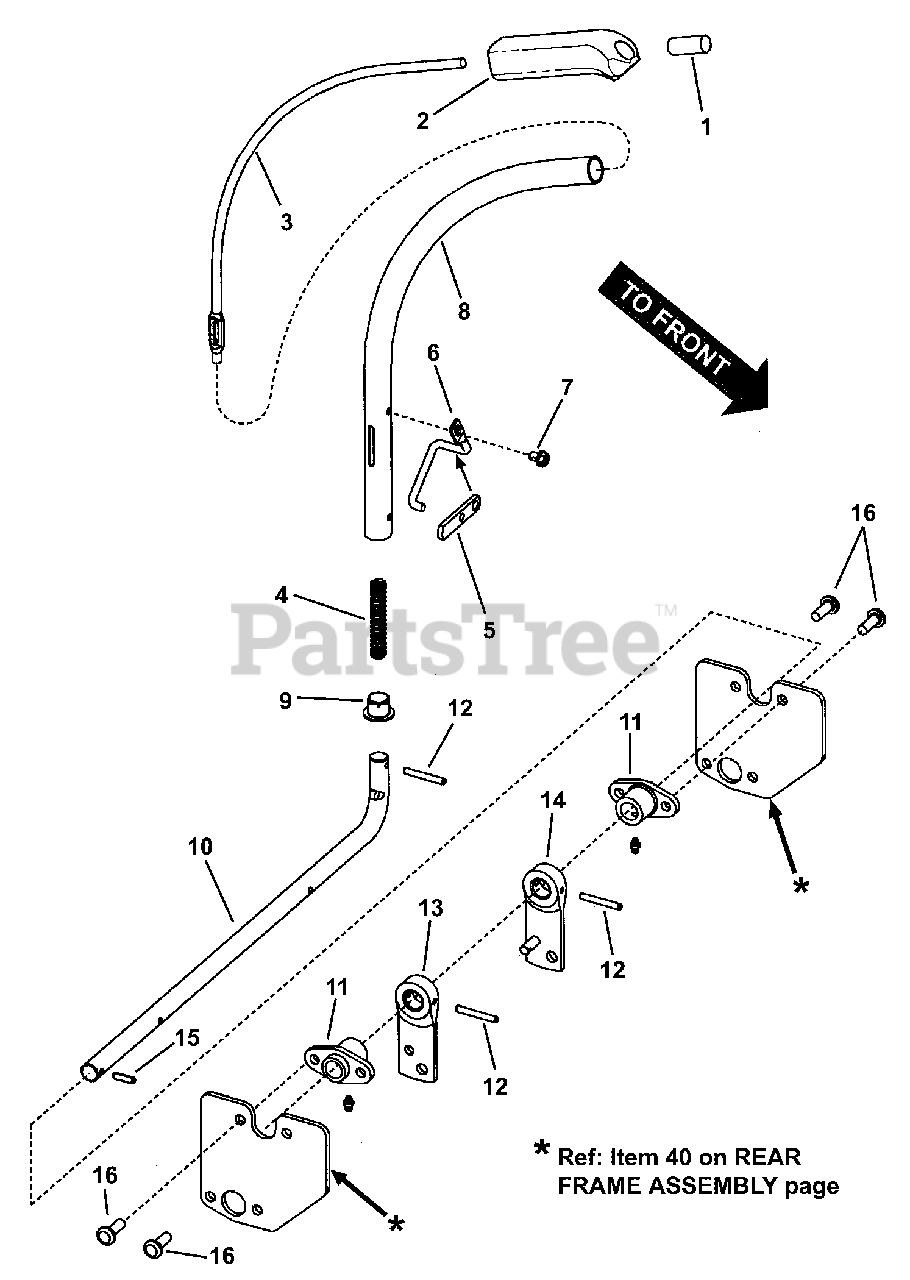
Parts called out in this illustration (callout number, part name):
1	BUTTON, Park Brake
2	GRIP, Brake/Clutch Handle
3	ROD, Park Brake
4	SPRING, Clutch/Brake Release
5	ARM, Brake/Clutch Lever
6	PIVOT, Brake/Clutch Lever
7	SCREW, 1/4-20 x 3/8" Hex Washer Self-Tap
8	TUBE, Park Brake
9	BUSHING, Nylon
10	ROD, Brake Actuation
11	PIVOT, Foot Shaft Assy (weldment 23170 with grease fitting, 13864)
12	ROLL PIN, 3/16 x 1-1/2"
13	ARM, Brake/Clutch
14	WELDMENT, Brake/Clutch Arm
15	ROLL PIN, 3/16 x 3/4"
16	SCREW, 5/16-18 x 7/8" Pan Head Self-Tap (Torx)
